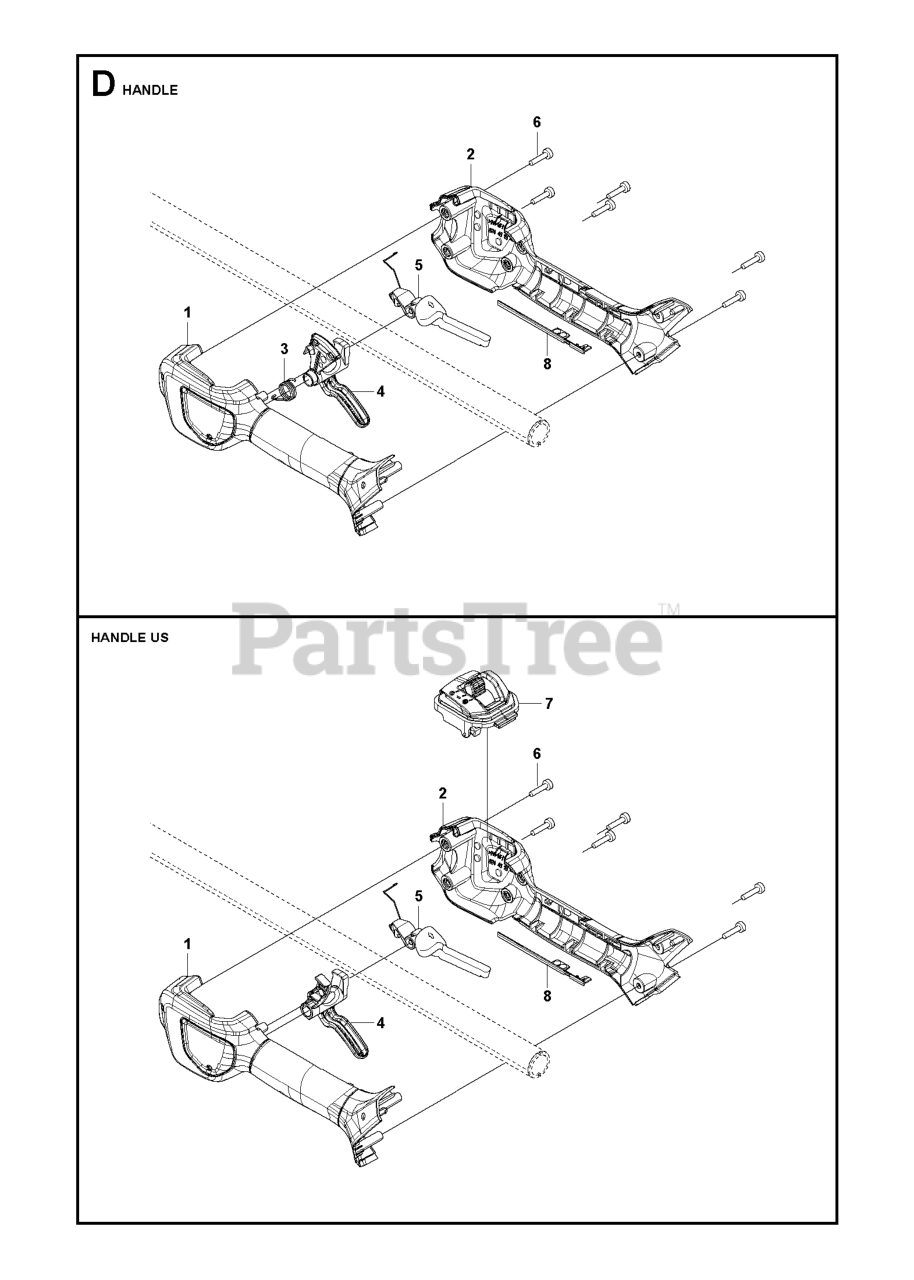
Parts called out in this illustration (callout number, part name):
1	Handles
2	Handles
3	Springs
4	Triggers
5	Throttles
6	SCREW ITXSCT PW4.2X18 10.9 ZN
7	Controls
